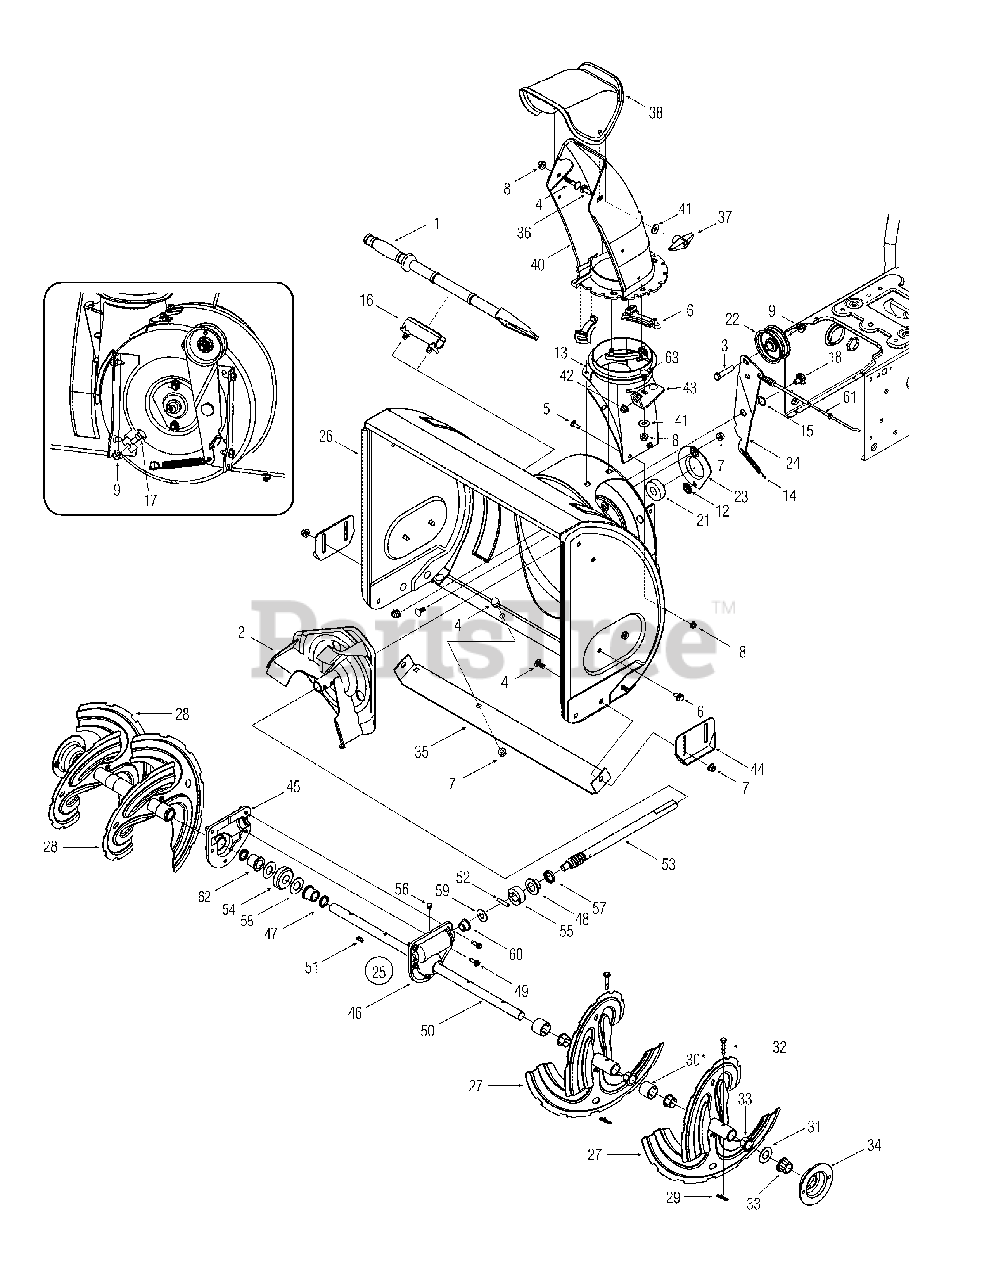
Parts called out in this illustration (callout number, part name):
1	Clean Out Tool
2	Impeller Assembly, 12" Diameter
3	Hex Screw, 3/8-16, 1.75, Gr5, Std
4	Bolt, Carriage, 5/16-18, .750 Gr1
5	Screw, Carriage, 1/4-20, .75, Gr5
6	Screw, Self-tapping, 5/16-12, 0.750
7	Nut, Flange Lock, 5/16-18, Grf, Nylon
8	Nut, Flange Lock, 1/4-20, Grf, Nylon
9	Nut, Flange Lock, 3/8-16, Grf, Nylon
10	Internal Cotter Pin
11	Cable, Tie, 3/16 x .05 x 7.4
12	Nut, Push-on, .25 Diameter
13	Chute, Adapter 5" Diameter
14	Spring, Extension, .38 OD x 3.6
15	Washer, Wave, .625 x.885 x.015
16	Mount, Clean Out Tool
17	Screw, Shoulder, .498 x .340, 3/8-16
18	Screw, Shoulder, .625 x .170, 3/8-16
19	Pin, Shear, .25 x 1.50, Gr2
20	Bearing, Hex Flange x .75 ID
21	Bearing, Ball, .75 ID x 1.85 OD
22	Idler Pulley, Flat 2.75 OD
23	Housing, Bearing, 1.85 ID
25	Gearbox Assembly, Auger, 30"
29	Cotter Pin, Bow-Tie
30	Spacer, 1.25 OD x .75 ID x 1.00
31	Washer, Flat, .76 x 1.49 x .06
32	Shear Pin, .25 x 1.50, Gr2
33	Bushing, Flange, .800 ID x .910 OD
34	Housing, Bearing, 1" Hex
36	Bolt, Carriage, 5/16-18, 1.0
37	Knob Assembly
38	Chute, Upper, w/ Domestic Label
39	Chute, Keeper Flange
40	Chute, Lower, 5.0 Diameter
41	Washer.349 ID x .879 OD x .063
42	Bushing, Plastic, .380
43	Bracket, Chute Crank
45	Housing, Auger, RH Reduced
46	Housing, Auger, LH Reduced
47	Seal, Oil, .750 ID
48	Bearing, Flange, .75 ID x 1.00 OD x .59
49	Screw, Self-tapping, 1/4-20, 0.750
50	Axle, Auger, 30"
51	Key, Hi-pro 3/16 x 5/8
52	Pin, Dowel, .25 OD x 1.2
53	Shaft, Worm .75 OD
54	Gear, Worm 20T
55	Collar, Thrust
56	Plug, 1/4 x .437
57	Seal, Oil, .75 x 1 x .131
58	Washer, Flat, .760 ID x 1.5 OD
59	Washer, Flat, .51 x 1.12
60	Bearing, Flange, .75 ID x 1.00 OD x .925
61	Auger Clutch Cable, 44.75"
62	Bearing, Flange, .75 ID x 1.00 OD x .975
63	Bolt, Carriage, 5/16-18, 1.0 Gr1
